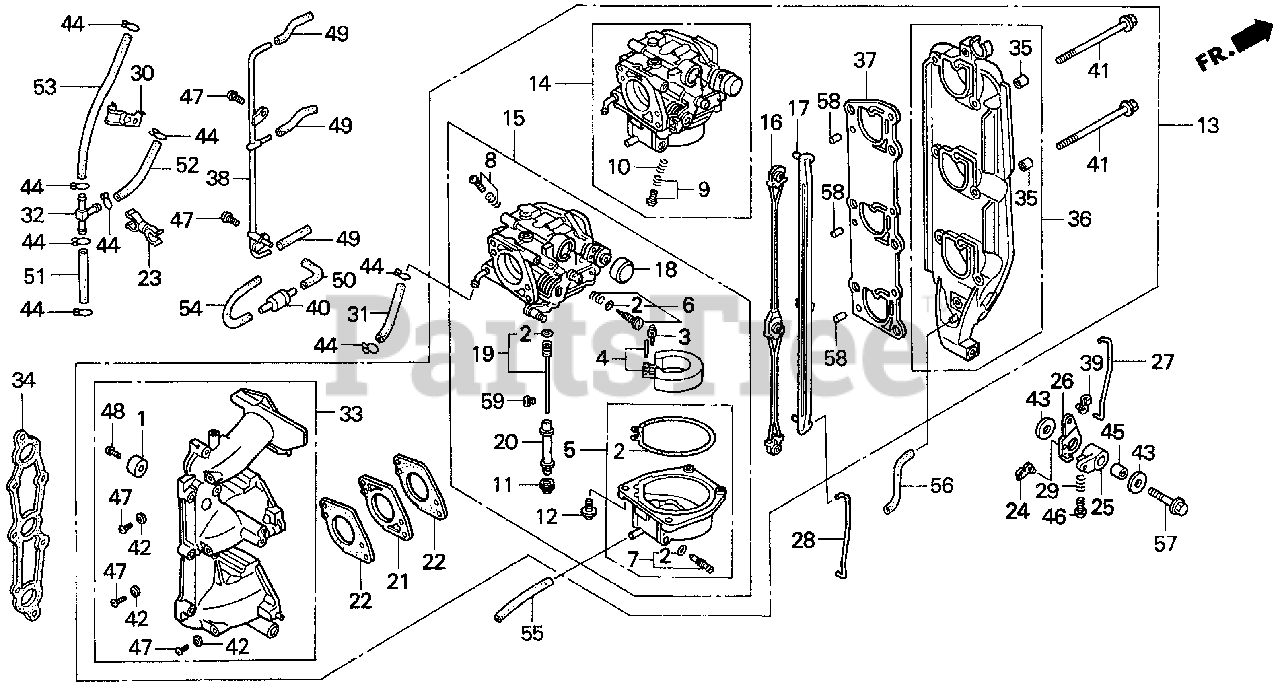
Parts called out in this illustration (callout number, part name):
1	METAL, ANODE
2	GASKET SET
3	VALVE SET, FLOAT
4	FLOAT SET
5	CHAMBER SET, FLOAT
7	SCREW SET, DRAIN
11	SCREW, PLUG
12	SCREW-WASHER
13	CARBURETOR ASSY. (BG30C C) *NH8* (DARK GRAY)
13	CARBURETOR ASSY. (BG30C A) *NH8* (DARK GRAY)
14	CARBURETOR ASSY. (#1/#2)
14	CARBURETOR ASSY. (#1,#2)
15	CARBURETOR ASSY. (#3)
16	LEVER, LINK
17	LINE, CHOKE
18	CAP, CHOKE DUST
19	JET SET (#102)
20	NOZZLE, MAIN
21	INSULATOR, CARBURETOR
22	GASKET, CARBURETOR
23	CLAMP, FUEL TUBE (A)
24	JOINT, ROD
25	ARM A, CHOKE
26	ARM B, CHOKE
27	ROD, CHOKE
28	ROD, CHOKE KNOB
29	SPRING, CHOKE ARM ADJUSTING
30	CLAMP, FUEL TUBE
31	TUBE C, FUEL
32	PIPE, THREE WAY JOINT
33	MANIFOLD, IN. *NH8* (DARK GRAY)
34	GASKET, IN. MANIFOLD
35	COLLAR, DISTANCE (6.5X11X7.5)
36	PLATE, MUFFLER
37	GASKET, MUFFLER PLATE
38	PIPE, INSTALL
39	BUSH, LINKAGE
40	VALVE, DASHPOT CHECK
41	BOLT, FLANGE (6X97)
42	WASHER, SEALING (5MM)
43	WASHER, PLAIN (6MM)
44	CLIP, TUBE (B10)
45	COLLAR, DISTANCE (6.5X10.5X16)
46	SCREW, PAN (4X16)
47	SCREW, PAN (5X10)
48	SCREW, PAN (6X18)
49	BULK HOSE, FUEL (3.5X3000) (3.5X45)
50	BULK HOSE, FUEL (3.5X3000) (3.5X60)
51	BULK HOSE, FUEL (5.5X3000) (5.5X65)
52	BULK HOSE, FUEL (5.5X3000) (5.5X110)
53	BULK HOSE, FUEL (5.5X3000) (5.3X170)
54	TUBE D, FUEL
55	BULK HOSE, VINYL (3.5X6.5X8000) (3.5X6.5X160)
56	BULK HOSE, VINYL (3.5X6.5X8000) (3.5X6.5X200)
57	BOLT, FLANGE (6X28)
58	ROLLER (6X15)
59	JET, MAIN (#88)
59	JET, MAIN (#90)
59	JET, MAIN (#92)
